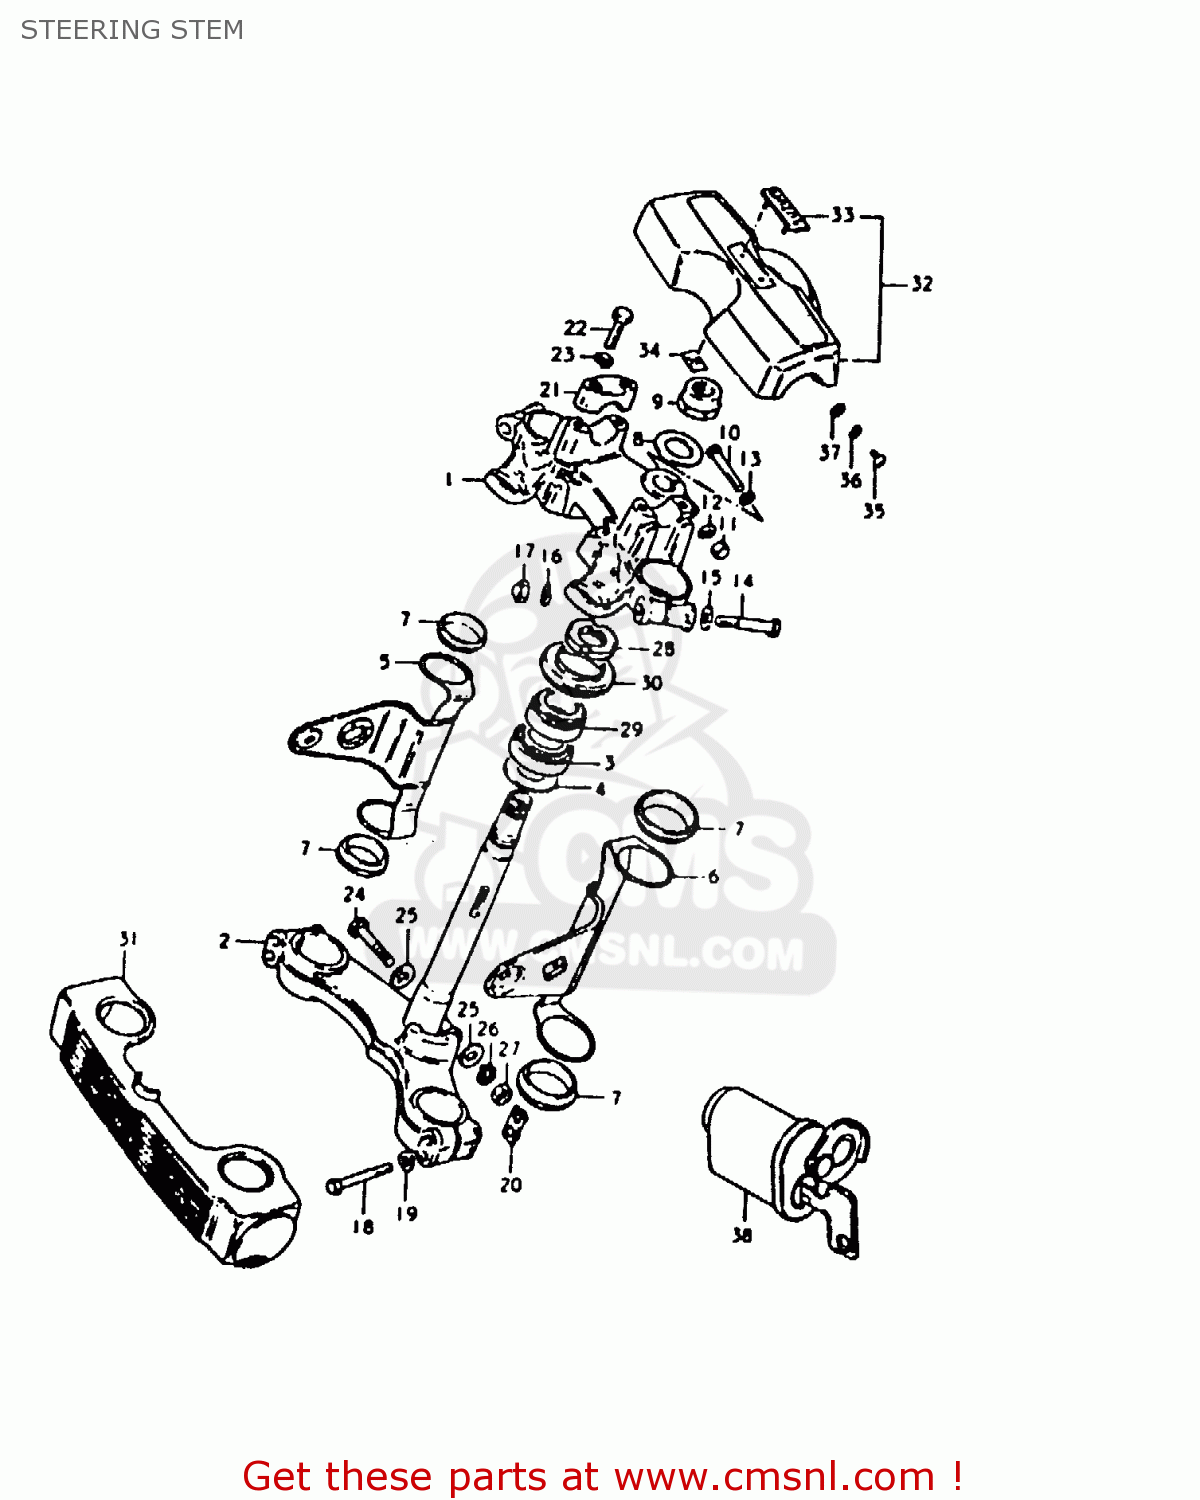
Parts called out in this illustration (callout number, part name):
1	HEAD,STEERING STEM
2	STEM,STEERING
3	BEARING
4	WASHER,THRUST
5	BRACKET,HEADLAMP,RIGHT
6	BRACKET,HEADLAMP,LEFT
7	CUSHION,HEADLAMP BRACKET
8	WASHER
9	NUT,FR FORK UPR BRACKET
10	BOLT 8X50
11	NUT
12	LOCK WASHER
13	WASHER
14	BOLT 10X55
15	WASHER
16	LOCK WASHER
17	NUT, LOWER LH
18	BOLT 8X55
19	WASHER
20	NUT,FR FORK INNER TUBE
21	HOLDER,HANDLE(BLACK)
22	BOLT
23	LOCK WASHER
24	BOLT
25	WASHER
26	LOCK WASHER
27	NUT
28	NUT,STEERING STEM(25X44X10)
29	TAPER,ROLLER BEARING
30	DUST SEAL,STEERING,UPPER
31	COVER,FRONT FORK
32	PAD,HANDLEBAR
33	EMBLEM,HANDLE COVER PAD
34	NUT
35	SCREW
36	LOCK WASHER
37	WASHER
38	LOCK ASSY, STEERING (NEIMAN TYPE EXECUTE
